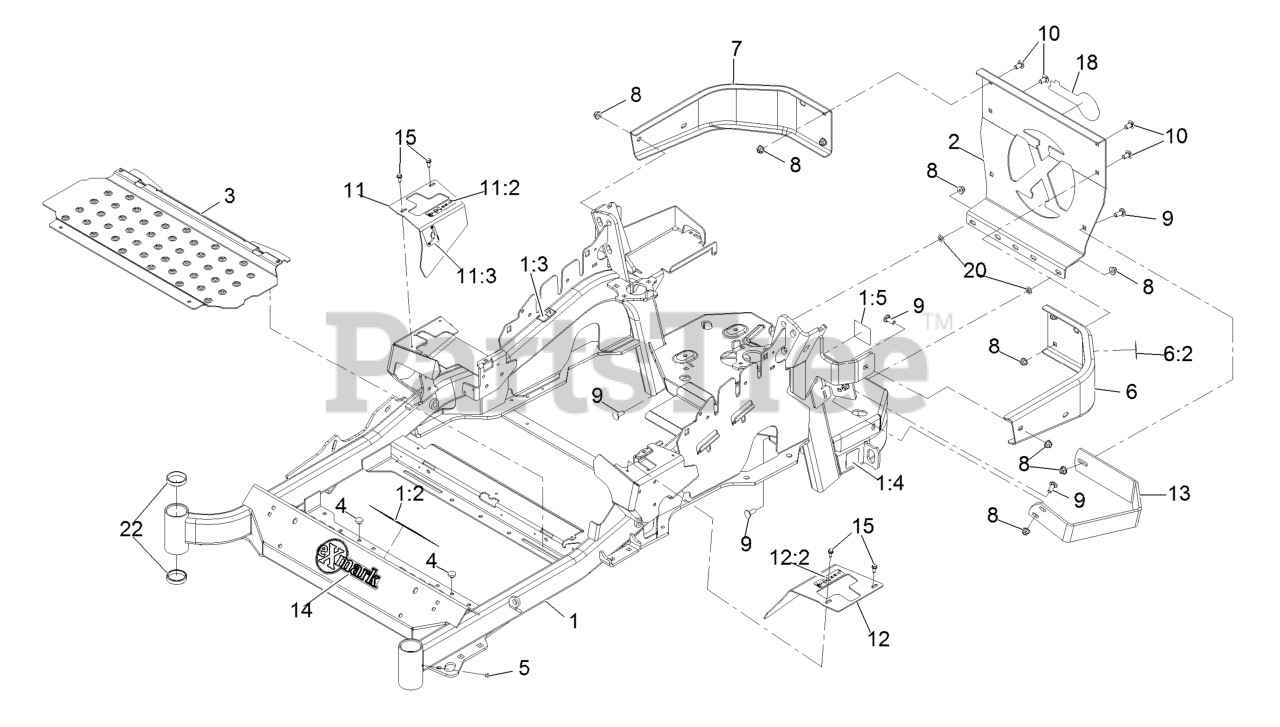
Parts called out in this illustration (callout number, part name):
1	Mainframe ASM
1:2	Decal-Danger
1:3	Decal-Warning
1:4	Decal-Hazard, Pinched Finger
1:5	Decal-Spark Arrester
2	Plate,Rear Guard
6	LH Bumper ASM
6:2	Decal-Warning
7	Bumper-RH
8	Nut-Nyloc 3/8-16 Flg
9	Bolt-Carriage 3/8-16 X 1
10	Bolt-Carriage 3/8-16 X 3/4
11	RH Motion Control Cover ASM
11:2	Decal-Control, Motion
11:3	Decal-Park Brake, CE
12	LH Motion Control Cover ASM
12:2	Decal-Control, Motion
13	Guard-Muffler
14	Decal-Exmark
15	Screw-HWH 1/4-20 X .62
18	Decal-Exmark Logo
20	Nut-Push 3/8-16
22	Cup-Bearing Tapered Roller
